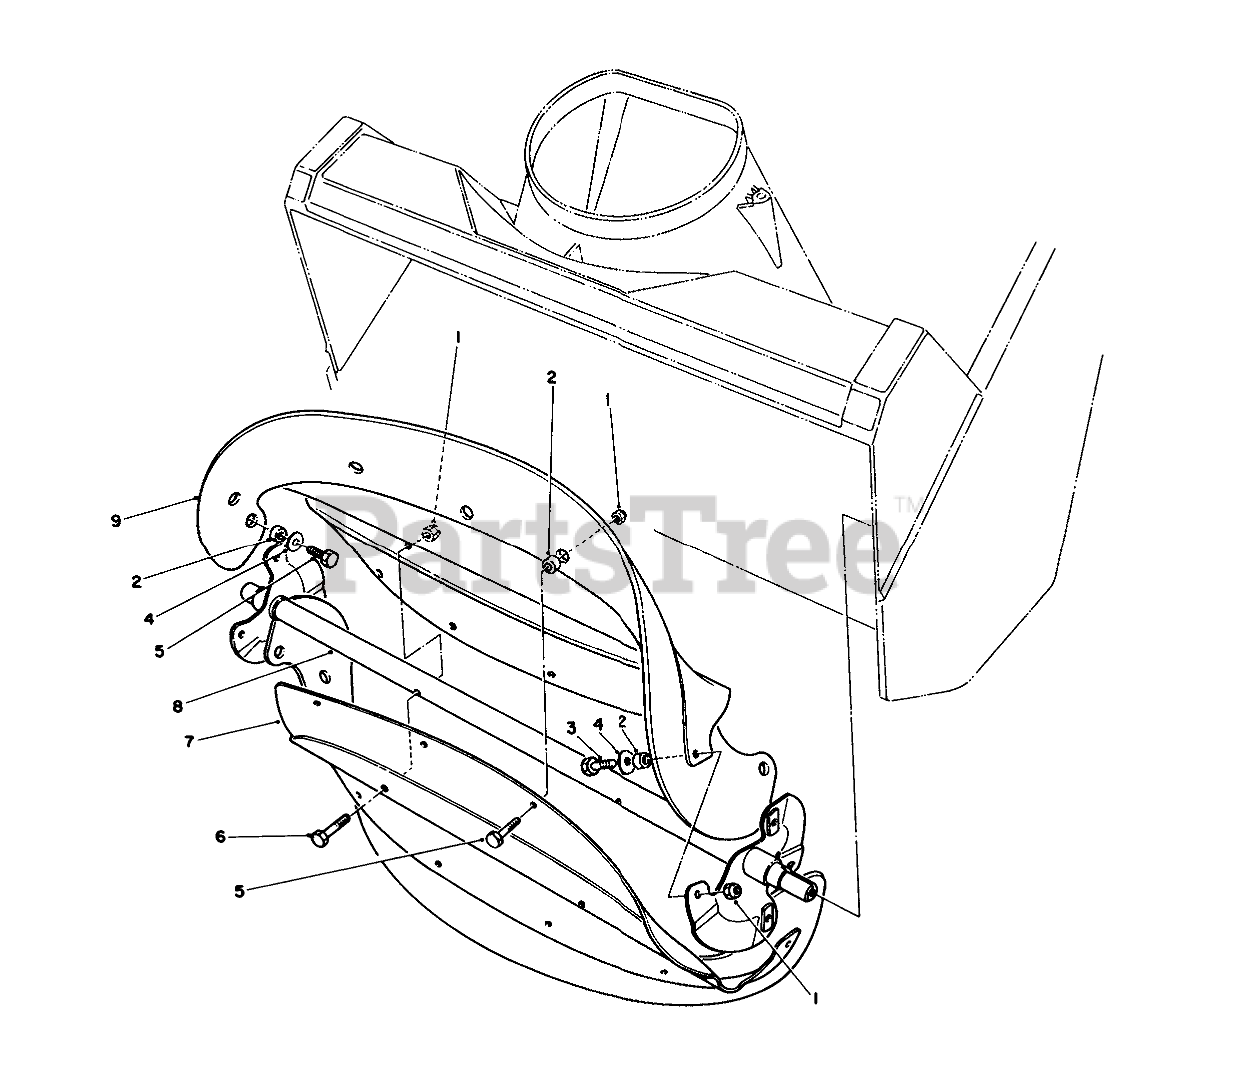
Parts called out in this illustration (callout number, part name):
1	NUT-LOCK, NI
2	SPACER-BLADE, ROTOR
3	SCREW-HH
4	WASHER-FLAT
5	SCREW-HH
6	SCREW-HH
7	ROTOR
8	ROTOR WA
9	Blade-Rotor
